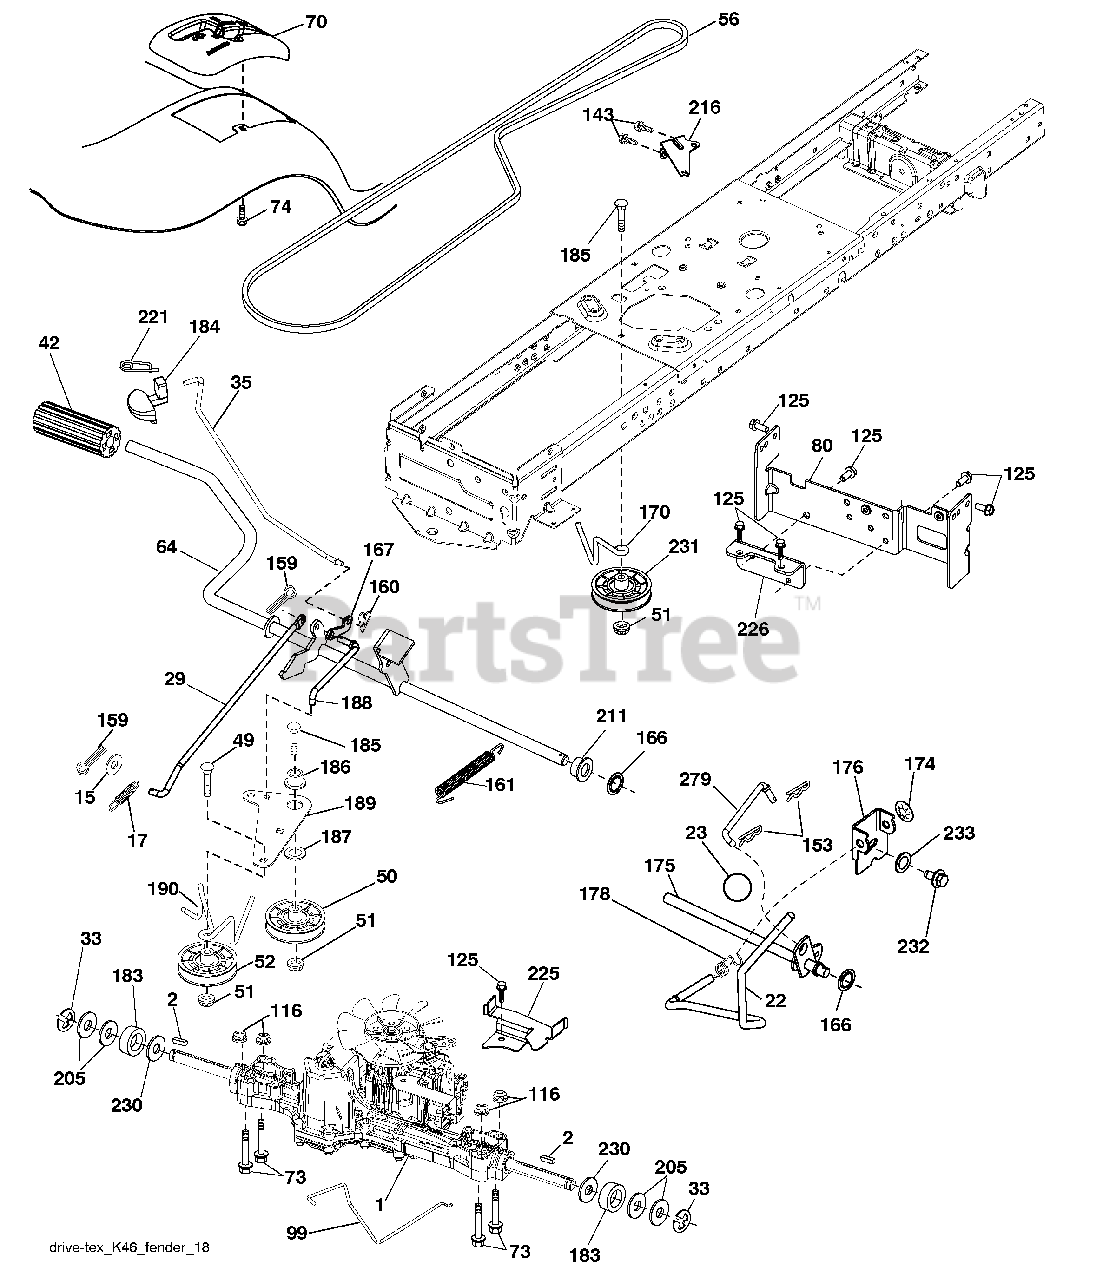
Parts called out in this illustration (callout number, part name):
2	Key Square
15	Washer 13/32 x 13/16 x 16 Ga.
17	Spring, Brake
22	Rod Shift
23	Knob
29	Rod, Brake
33	Ring E
35	Rod, Brake, Park
42	Cover, Foot Pedal
49	Bolt
50	Pulley Idler Flat
51	Lock Nut 3/8-16
52	Idler V-Groove 910" Offset
56	V-Belt, Drive
64	Shaft Asm. Pedal Brake Control
70	Console
73	Bolt Hex 5/16-18 Gr. 5
74	Screw 1/4 x 1/2
80	Strap Torque
99	Rod Spring Bypass
116	Nut Lock Hex Flange 5/16-18
125	Screw 5/16-18 x 3/4
143	Screw THDROL 5/16-18
153	Retainer Spring 1"
159	Pin Cotter 1/8 x 3/4
160	Retainer Clip
161	Spring, Return, Clutch
166	Nut Push .625
167	Latch Brake Parking
170	Keeper Belt Centerspan
174	Nut Push
175	Shaft Asm Shift
176	Arm Clevis Rod Shift
178	Spring Shift
183	Spacer Axle
184	Handle Parking Brake
185	Bolt
186	Spacer Retainer
187	Washer
188	Link Clutch Ground Drive
189	Bellcrank Ground Drive
190	Keeper Bellcrank Ground Drive
205	Washer 25/32 x 1-5/8 x 16 Ga.
211	Bushing Shaft
216	Bracket Pulley Idler
221	Retainer Spring Clip Handle
225	Keeper Belt Transaxle
226	Bracket Mount Torque
230	Washer Harden .793 x 1.637 x 060
231	Idler V-Groove 1.688" Offset
232	Bolt 7/16-14 x 1 Gr 5
233	Washer Serrated
279	Link Shift
